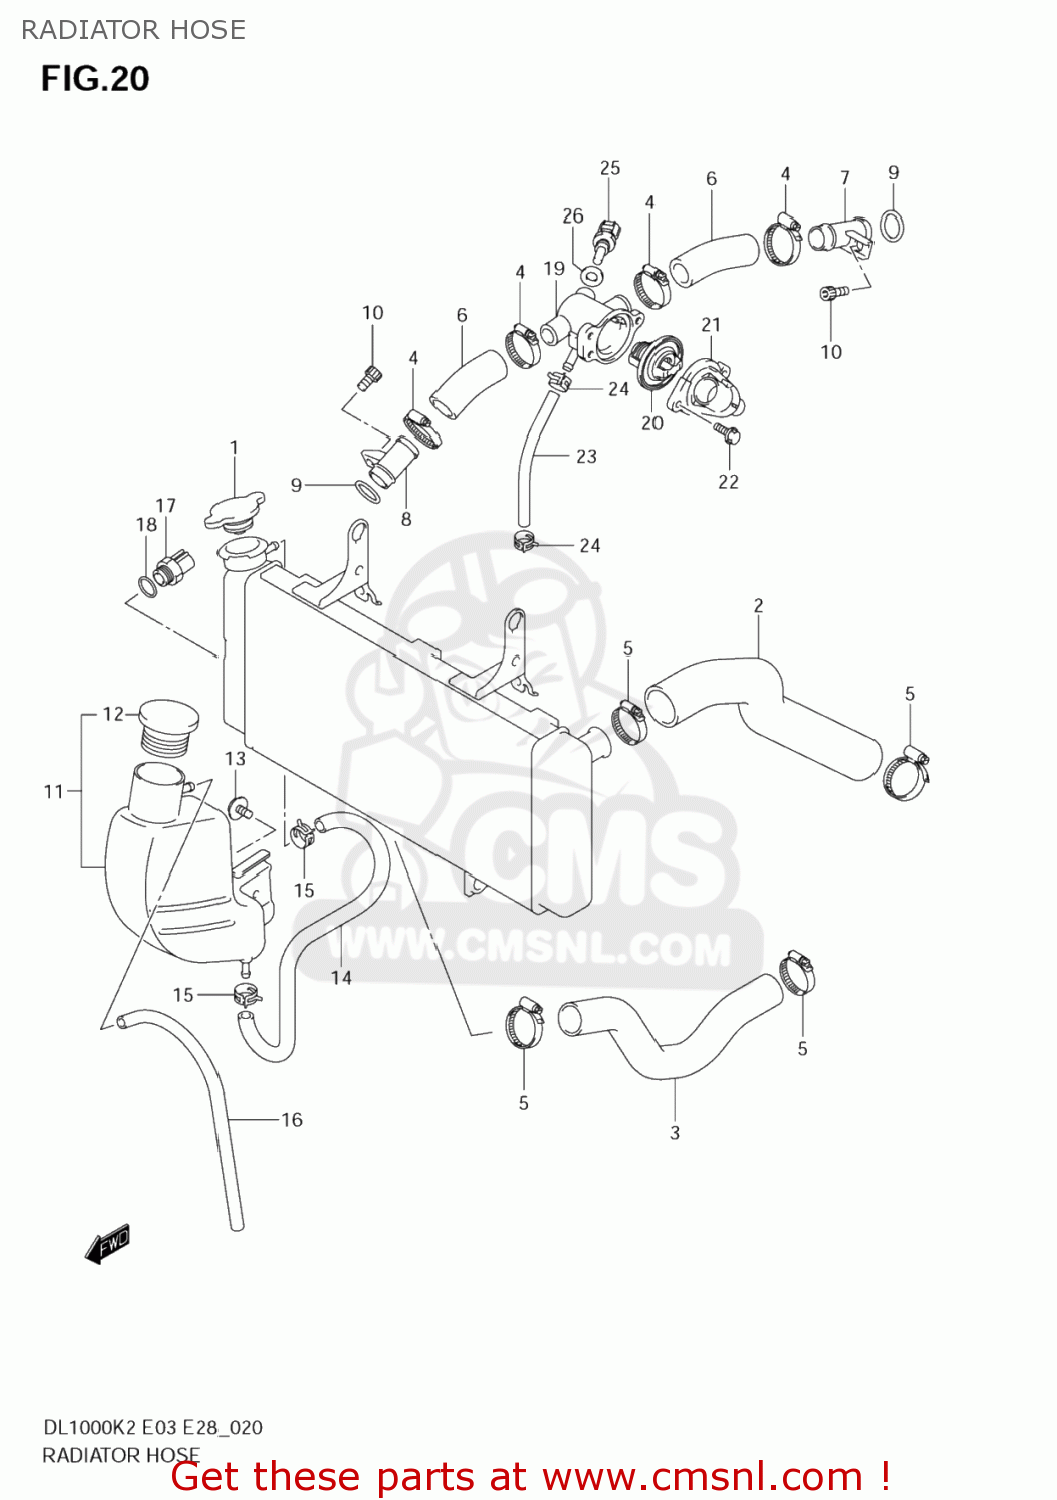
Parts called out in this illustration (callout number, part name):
1	CAP COMP,RADIATOR
2	HOSE,RADIATOR INLET
3	HOSE,RADIATOR OUTLET
4	CLAMP
5	CLAMP
6	HOSE,CONNECTOR INLET
7	UNION,CONN HOS
8	UNION,CONN HOSE FR
9	O RING(D:3.2,ID:17.8)
10	BOLT,STRANGER
11	TANK ASSY,RESE
12	CAP,WATER RESERVOIR TANK
13	BOLT(6X13)
14	HOSE,RESERVOIR TANK INLET
15	CLIP
16	HOSE(5X9X2000)
17	SWITCH,RADIATOR FAN
18	O-RING
19	CONNECTOR,THERMOSTAT INLET
20	THERMOSTAT,WATER
21	CAP,THERMOSTAT CONNECTOR
22	BOLT
23	HOSE,WATER BYPASS
24	CLAMP
25	SENSOR,WATER TEMP
26	GASKET(12X17X1) (NAS)
